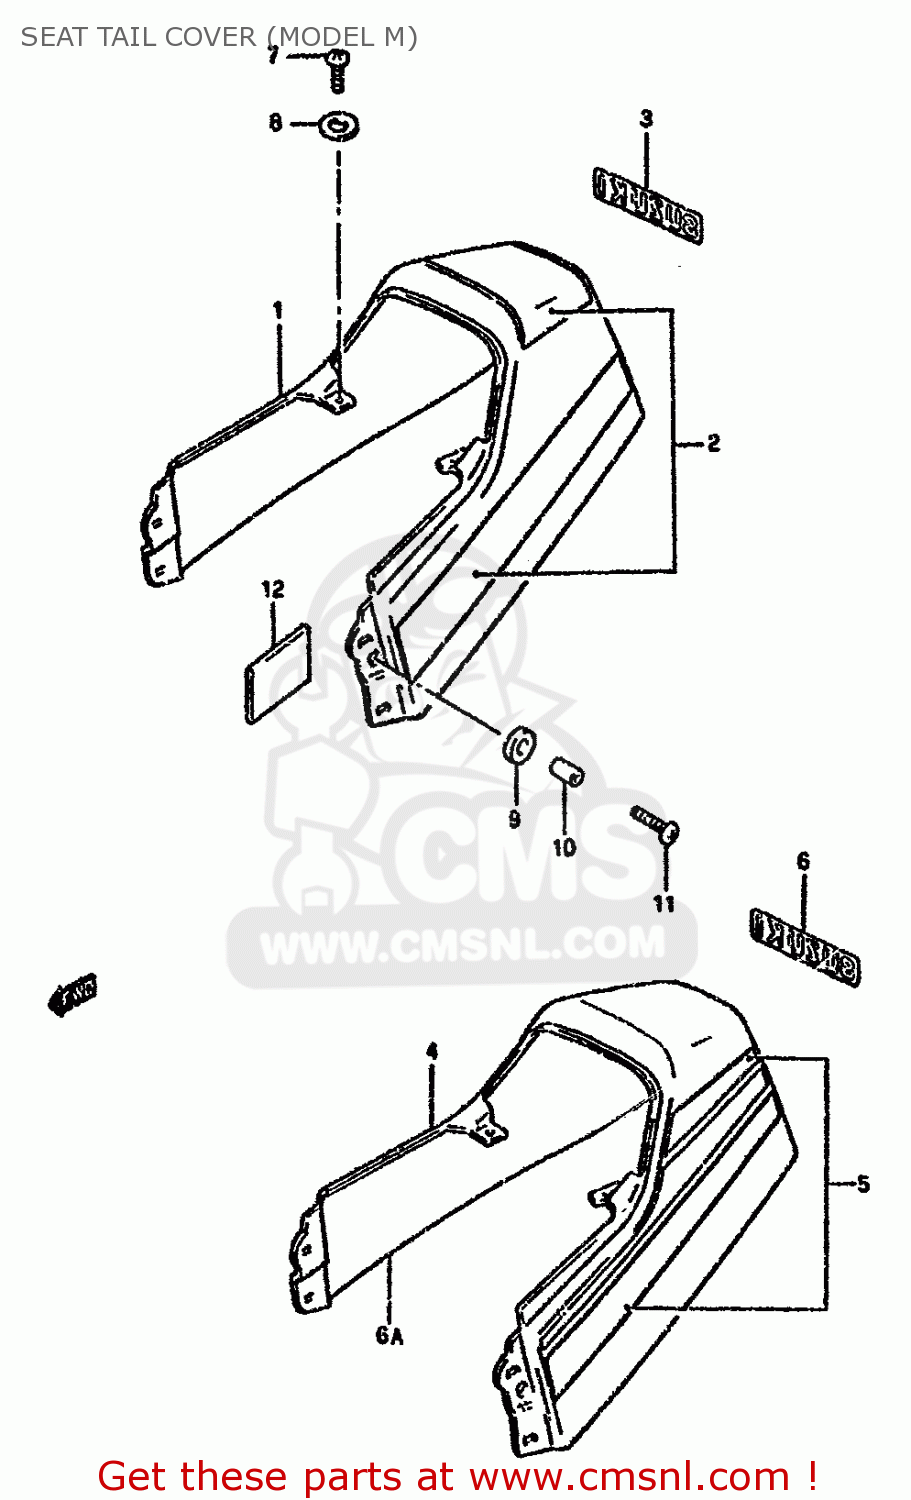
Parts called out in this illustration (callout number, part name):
1	COVER,SEAT TAIL (BLACK)
2	TAPE SET, SEAT TAIL
3	EMBLEM
4	COVER,SEAT TAIL (WHITE)
5	TAPE SET, SEAT TAIL
6	EMBLEM
6A	COVER,SEAT TAIL (GRAY)
7	SCREW
8	WASHER
9	CUSHION
10	SPACER
11	SCREW(6X16)
12	CUSHION
13	EMBLEM(WHITE)
14	COVER,SEAT TAIL (ORANGE)
15	TAPE SET,TAIL COVER
16	EMBLEM
17	SCREW
18	WASHER
19	WASHER(6.5X18X1)
20	SPACER
21	CUSHION
22	SCREW
23	CUSHION
24	HOLDER,TOOL
25	WASHER
26	NUT 6MM
27	BAND
28	TOOL ASSY
